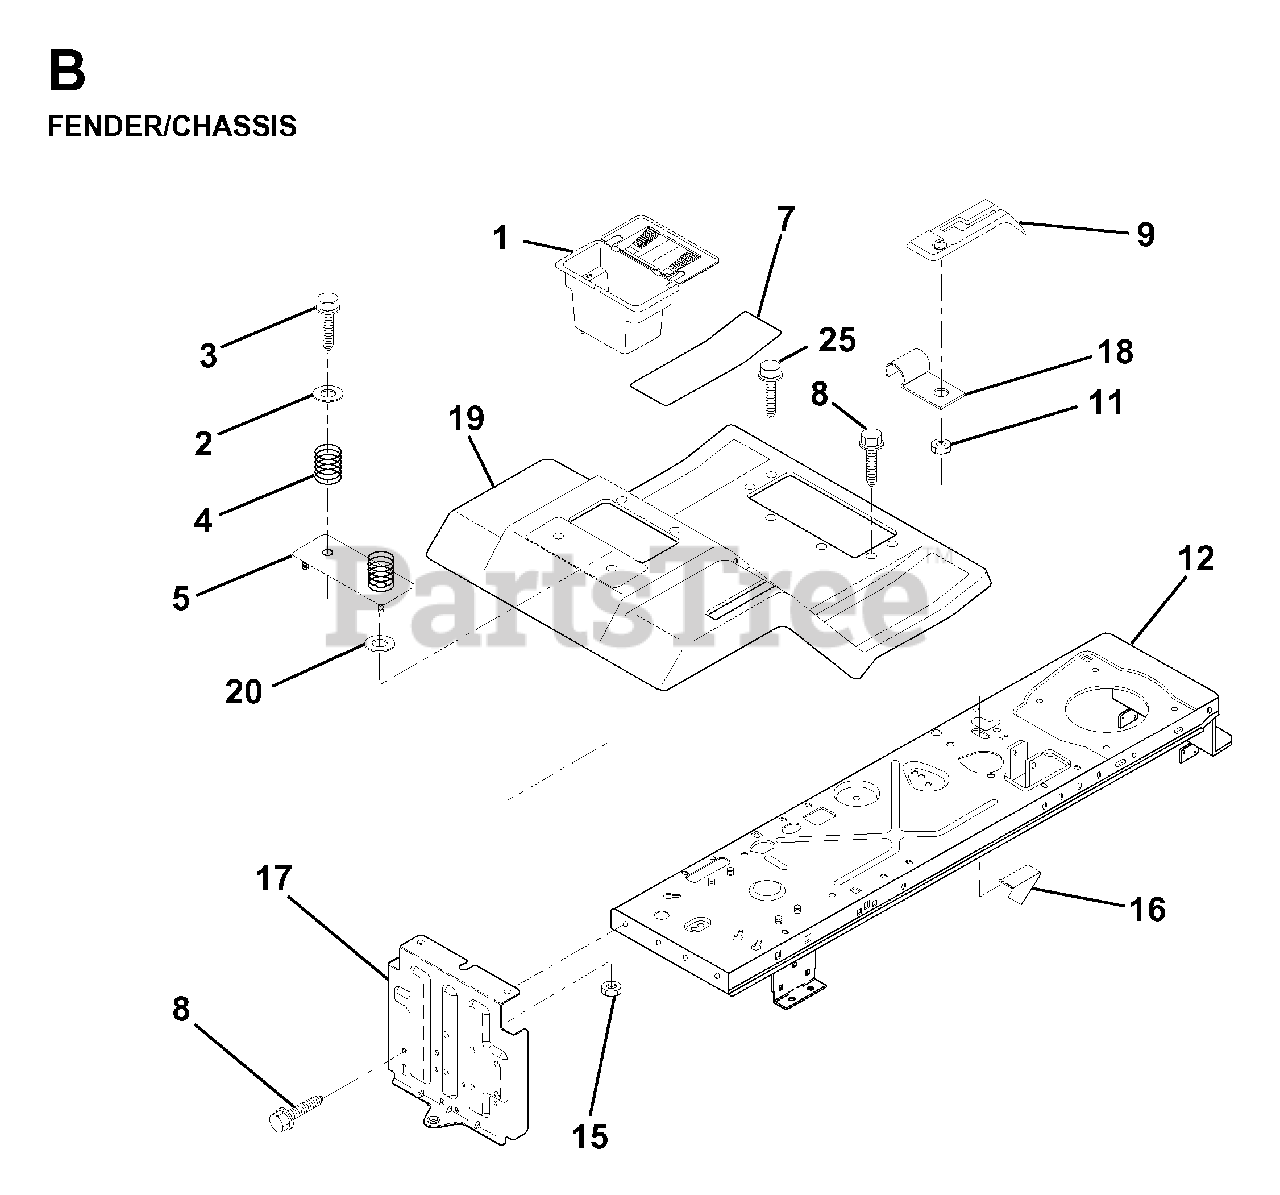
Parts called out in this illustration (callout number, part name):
1	CASE BATTERY MECH HINGE
3	SCREW
4	SPRING COMPRESSION
7	PAD FOOTREST
8	SCREW
9	CONSOLE SHIFT CTL
18	CLIP,INSULATOR
20	WASHER
